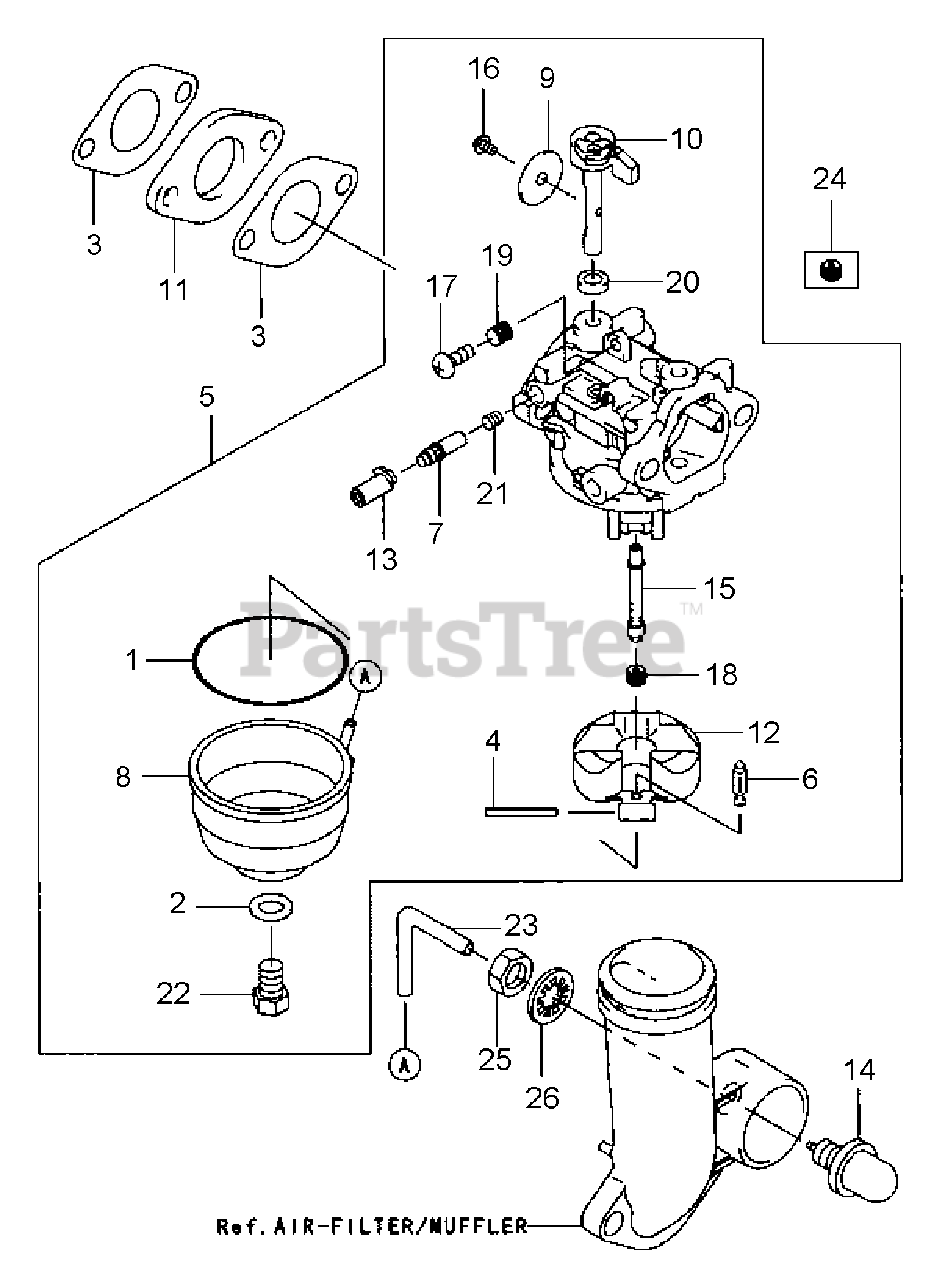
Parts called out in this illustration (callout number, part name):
3	Gasket
5	Carburetor Assy.
7	Pilot Air Screw
8	Float Chamber
9	Throttle Valve
10	Throttle Shaft
11	Insulator
18	Main Jet, #76
23	Tube, 2x5x65
25	Hex Nut, Fine
26	Toothed Washer
